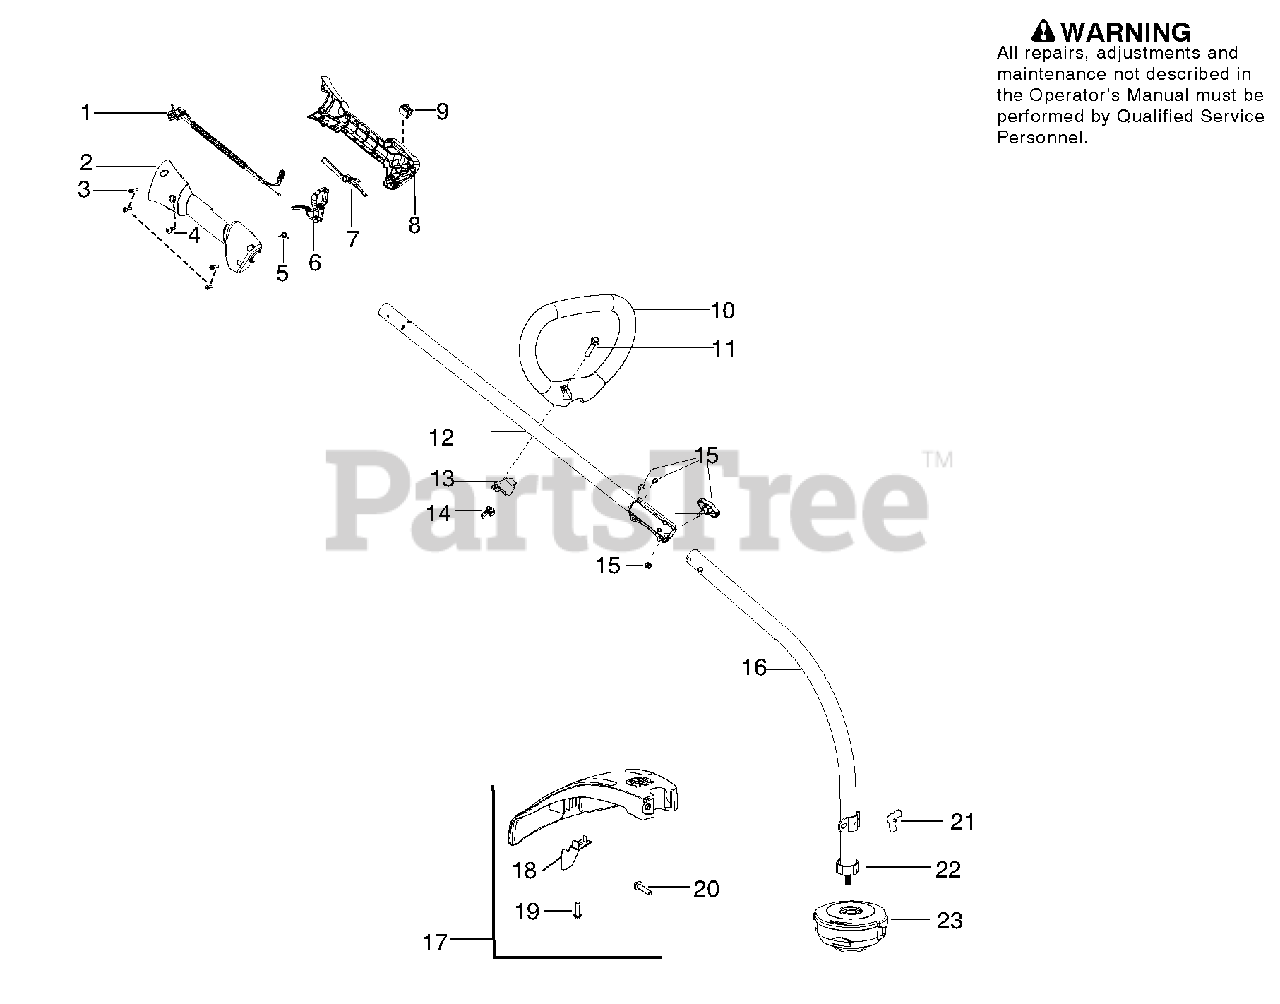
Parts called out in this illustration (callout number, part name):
1	Assy - Cable/Wire Harness
2	Housing - Throttle (RH)
3	Screw
4	Screw
5	Spring - Trigger
6	Trigger
7	Lockout - Throttle
8	Housing - Throttle (LH)
9	Kit - Switch
10	Handle - Assist
12	Kit - Driveshaft Upper
13	Clamp - Assist Handle
14	Wingnut
15	Kit - Knob / Screw
16	Kit - Lower Shaft
17	Kit - Shield
18	Limiter - Line
21	Wingnut
22	Dust Cup
23	Assy. - T25 Cutting Head
